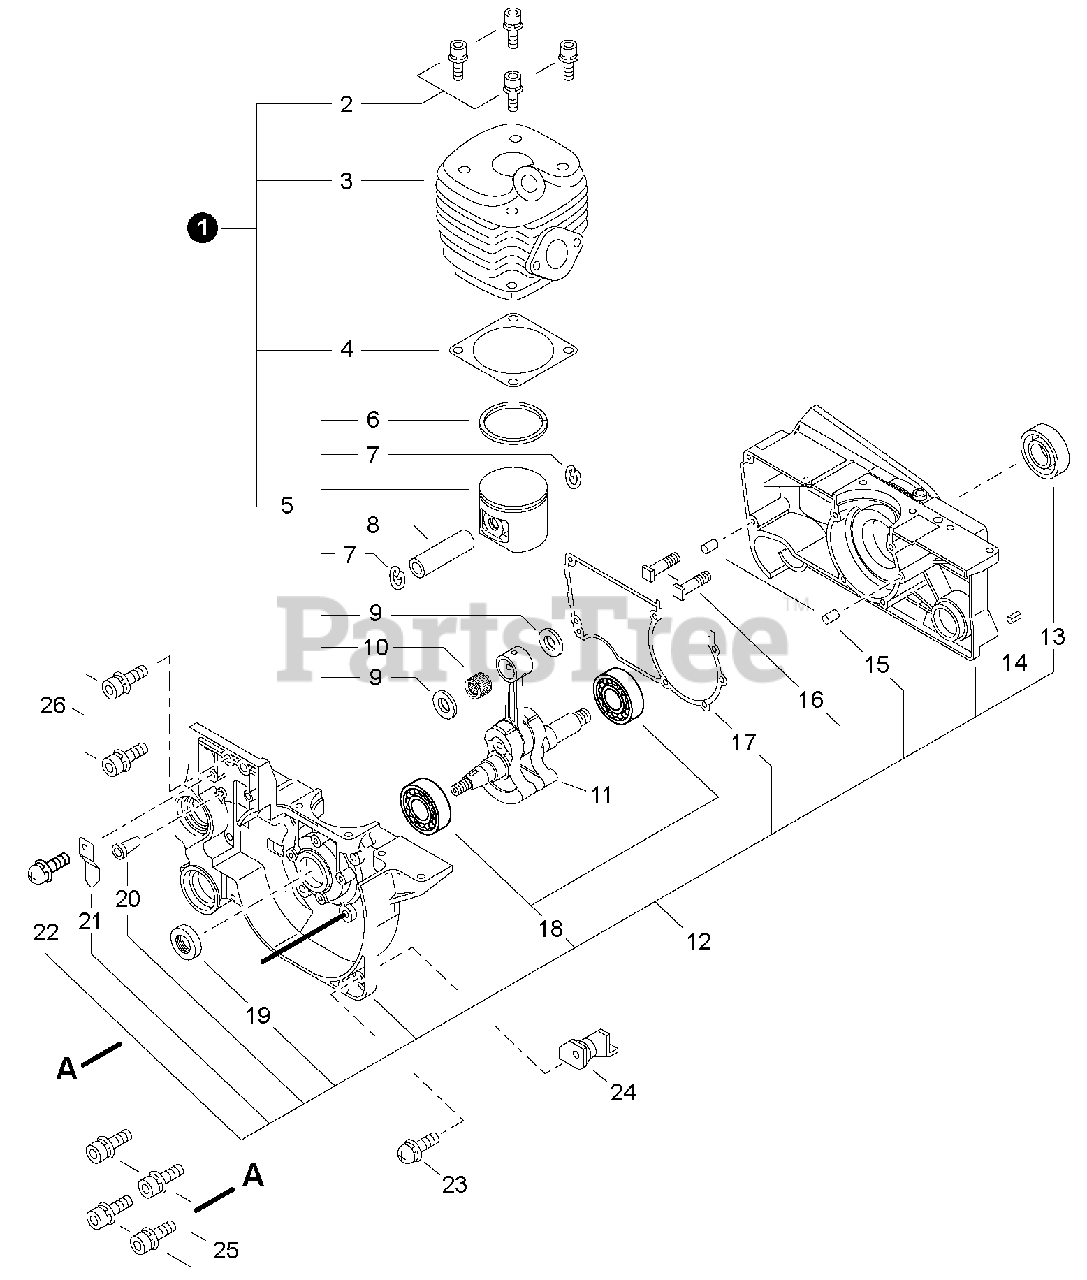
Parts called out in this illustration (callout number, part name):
1	CYLINDER/PISTON KIT
2	SCREW - 5X25
3	CYLINDER
4	GASKET, CYLINDER
5	PISTON KIT
6	RING, PISTON
7	RING, RETAINING
8	PIN, PISTON
9	SPACER, PISTON
10	BEARING, NEEDLE
11	CRANKSHAFT ASSY
12	CRANKCASE KIT
13	SEAL, OIL
14	PIN - SPRING -- 5X25
15	PIN - LOCATING
16	STUD, GUIDE BAR
17	GASKET, CRANKCASE
18	BEARING, BALL - 6202
19	SEAL, OIL
20	VENT, TANK
22	SCREW - 4X8
23	SCREW - 5X14
24	CUSHION
25	SCREW - 5X35
26	SCREW - 5X20
